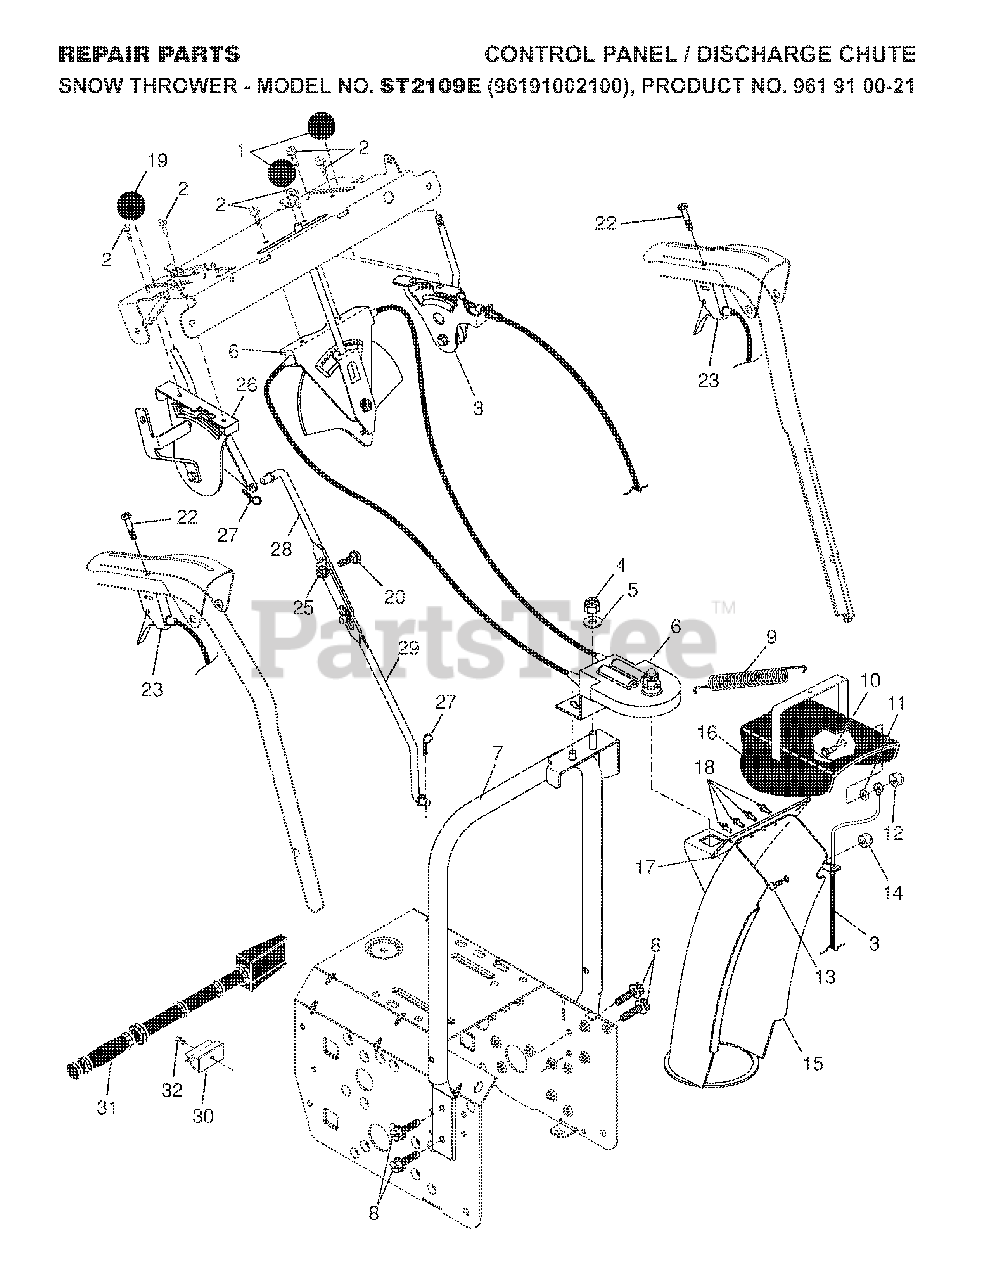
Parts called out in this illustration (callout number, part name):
1	KNOB LEVER, BLACK
2	SCREW #10-24 X 5/8
3	CONTROL.CABLE.DEFLECTOR
4	NUT
6	CONTROL.CABLE.CHUTE.RO
7	SUPPORT, PIVOT
8	SELF-TAPPING SCREW 5/16-18X3/4
10	BOLT, SHOULDER
11	WASHER, NYLON FRICTION
12	LOCKNUT
13	BOLT
14	NUT, LOCK 5/16-18
17	SEAL, DEFLECTOR
18	RIVET BLIND
19	RED KNOB SHIFTER
23	STEERING.CONTROL.SNOW THROWER
25	NUT.FLANGE.5/16
26	HEAD ASSY SPEED
27	SPRING RETAINER
28	ROD, UPPER SPEED CONTROL
29	ROD, LOWER SPEED CONTROL
30	CLIP.CLEANOUT.TOOL
31	CLEAN OUT TOOL
32	SCREW.HWH.13-16-5.8.BZP
